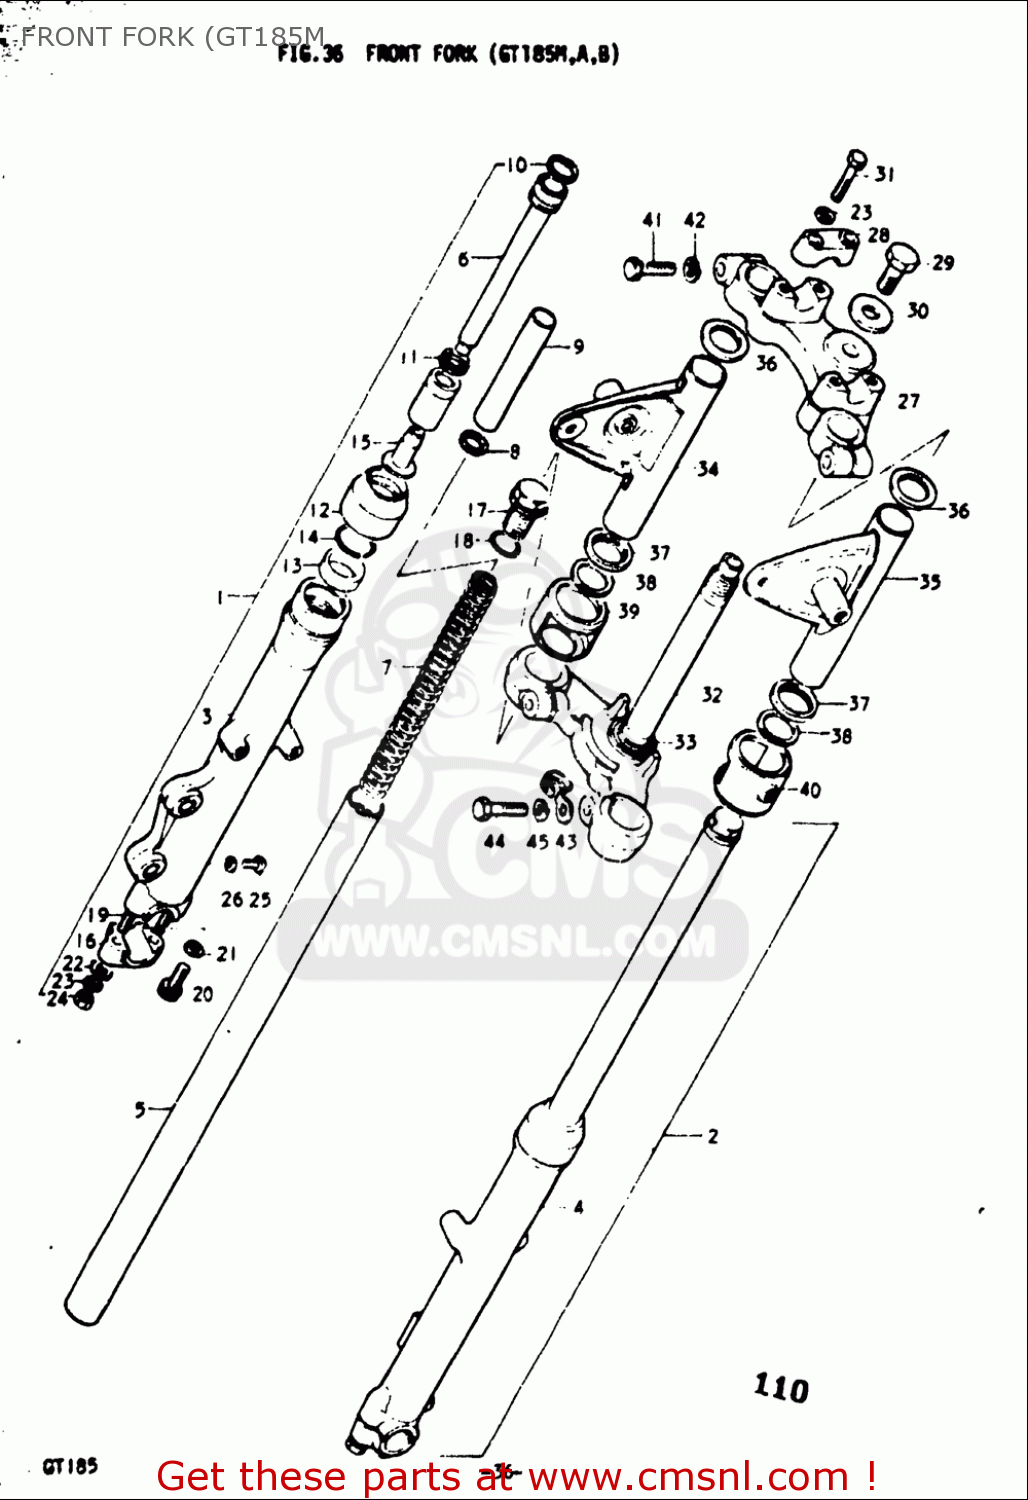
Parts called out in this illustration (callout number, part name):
5	TUBE,FORK,INNER
9	SPACER,FRONT FORK SPRING
12	SEAL,DUST
13	SEAL,OIL
14	SEAL,OIL STOPPER RING
18	O RING
19	STUD 8X25
20	BOLT(8X27)
21	GASKET (NAS)
22	WASHER
23	WASHER,LOCK
24	NUT
25	SCREW 4X6
26	GASKET (NAS)
28	HOLDER,HANDLE UPR
29	BOLT,FR FORK(10X33)
30	WASHER,STEM HEAD(10.5X30X3.2)
31	BOLT
33	RACE,STEERING OUTER LWR
34	BRACKET,HEADLAMP HOUSING
35	BRACKET,HEADLAMP,LEFT
41	BOLT
42	WASHER,LOCK
44	BOLT
45	WASHER,LOCK
